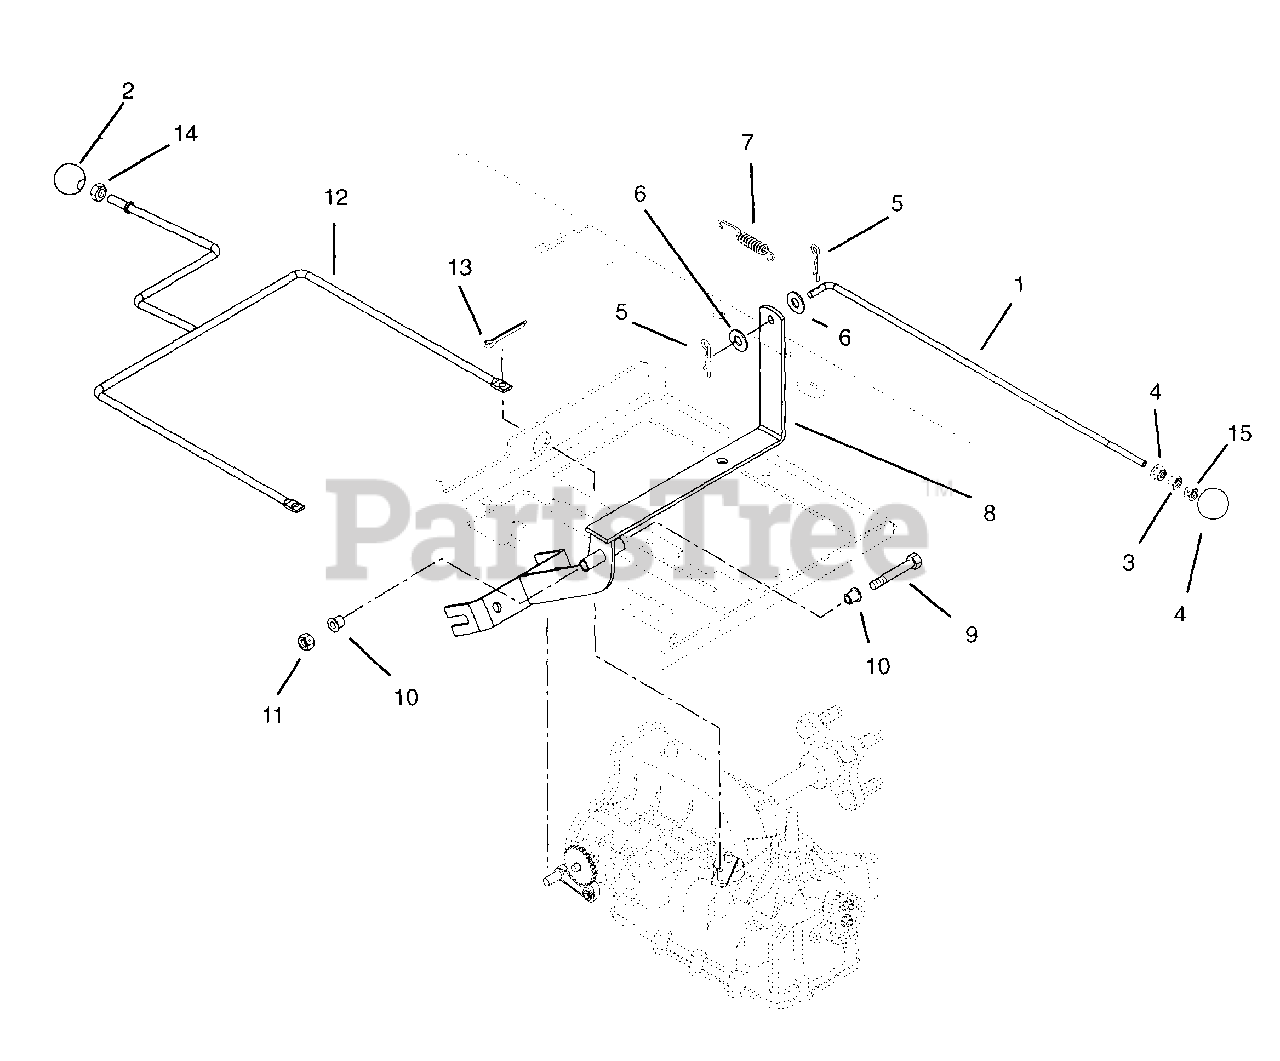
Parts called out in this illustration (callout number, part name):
1	BRAKE ROD
2	KNOB, BALL 5/16-18 X 1.5
3	@NUT-HEX .31-18 YWZC
4	@NUT-SPNLK-FLG .312-18 YWZC
5	PIN-HAIR INT .08X.18X1.18 YWZC
6	@WSHR-FL-STL.344X.688X.065YWZC
7	SG-TENS .051X.60X2.25 WLD 7.0
8	BRAKE ARM WELDMENT
9	@BLT-HEX .25-20X3.00 YWZC
10	BSHG-FLG .257X.38X1.080 NYL
11	@NUT-LK-CTR .25-20 YWZC
12	DUMP VALVE WELDMENT
13	PIN-HAIR INT .08X.18X1.18 YWZC
14	NUT- JAM .312-18 YWZC
15	@NUT-LK-CTR .31-18 YWZC
